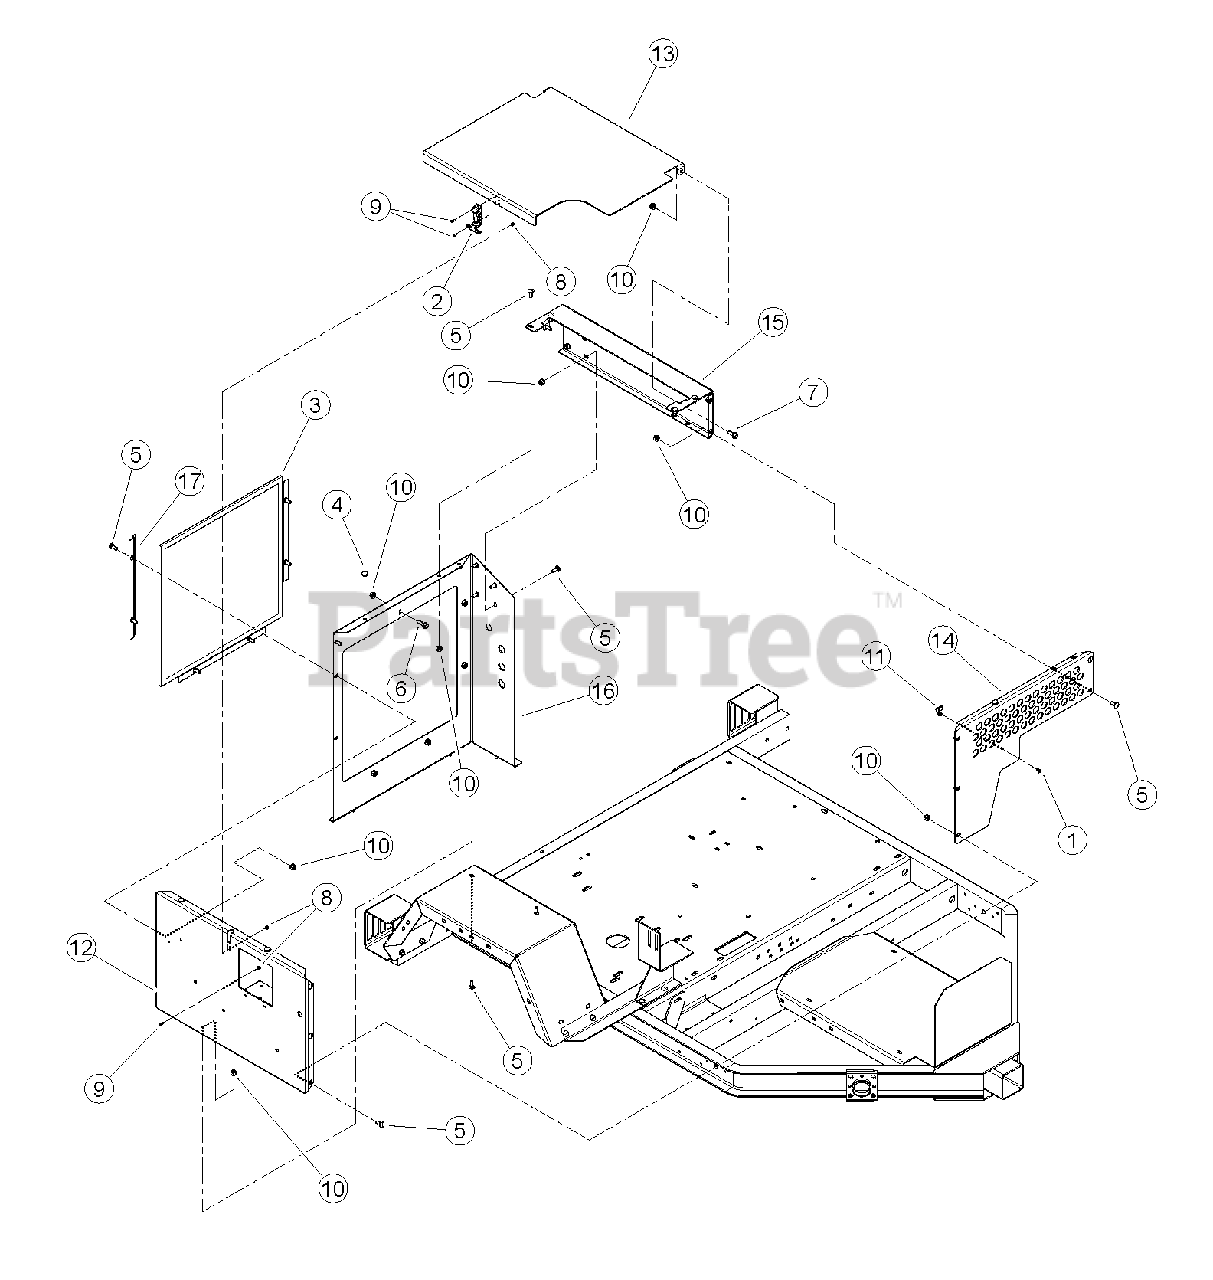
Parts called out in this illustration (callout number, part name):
1	RIVET, 1/4 X 3/4 ST POP
2	LATCH, FLEXIBLE DRAW
3	SCREEN, RADIATOR INLET
4	BUMPER, RUBBER
5	BOLT, 3/8 X 1" GR5 CRG NC ZP
6	BOLT, 3/8 X 1-1/4 FLANGE NC
7	BOLT, 3/8 X 1 FLANGE NC
8	NUT, 10/24 NYLOCK TYPE NM ZP
9	SCREW, MCH 10-24 X 1/2" PAN HD PH ZP
10	NUT, 3/8-16 NYLOCK FLANGE
11	CLAMP, CABLE MOUNT
12	WELDMENT, ENGINE SIDE
13	HOOD, ENGINE
14	COVER, FRONT ENGINE
15	SIDE, ENGINE COVER
16	COVER, RADIATOR
17	BRACKET, SCREEN HOLDER
